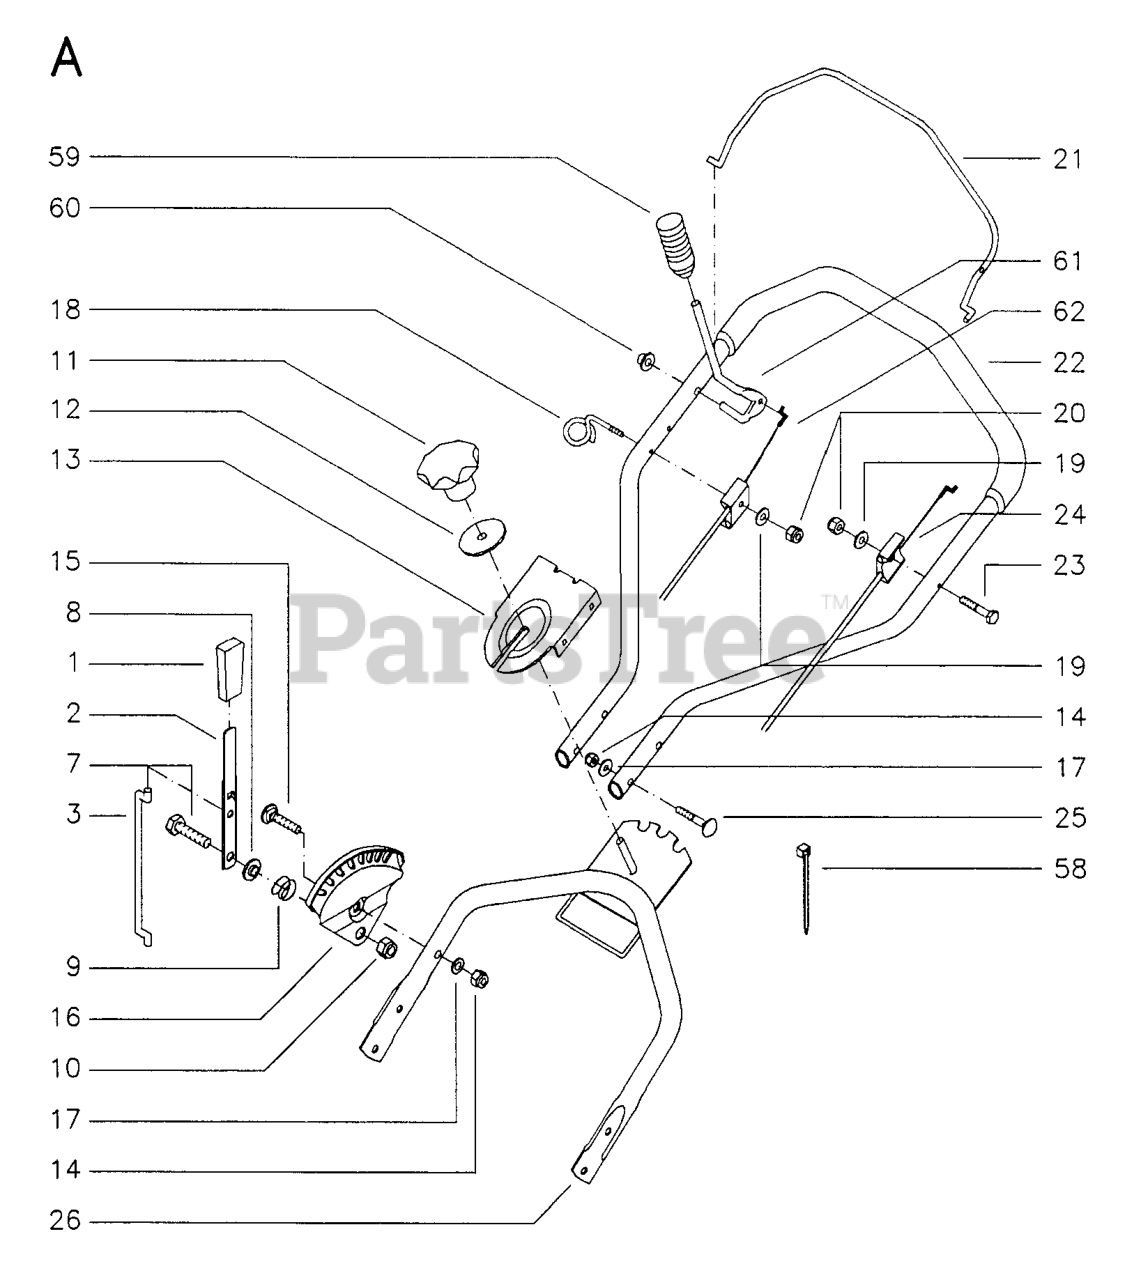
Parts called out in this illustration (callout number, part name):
2	CLUTCH ARM
9	PRESSURE SPRING
14	LOCKNUT M8
17	WASHER - 15X7.3X1.6
20	LOCKNUT M6
23	BOLT FLANGE
